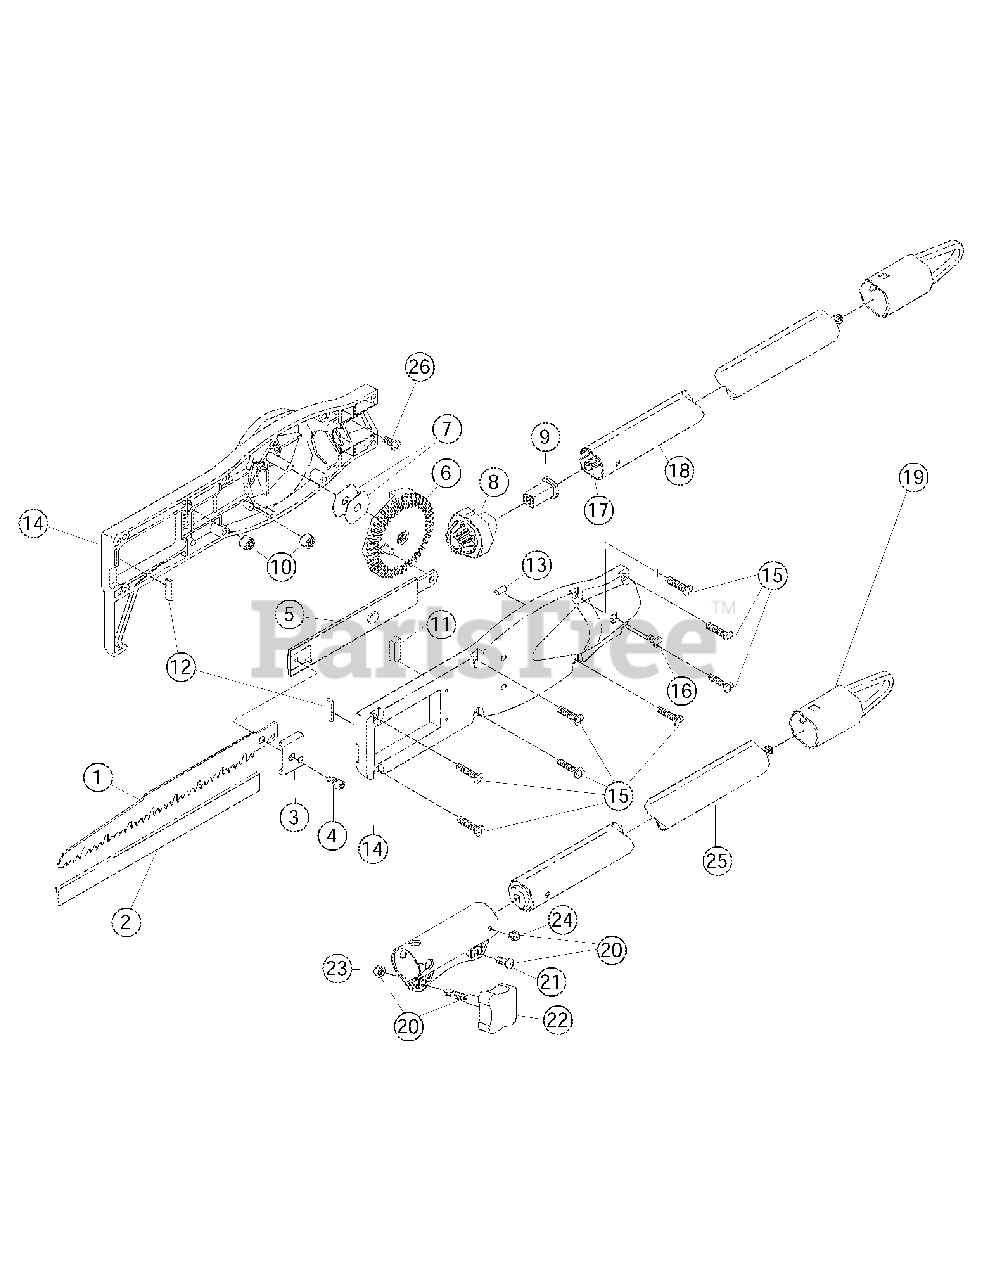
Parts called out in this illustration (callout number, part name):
1	Blade (2 pack)
2	Blade Cover
3	Blade Clamp
4	Blade Clamp Screw & Washer Assembly
5	Arbor Assembly
8	Pinion Bevel Gear
10	Slide Bushing
12	Slider (2-pack)
13	Rubber Plug
14	Housing set
15	Housing Screw (8 required)
16	Anti-Rotation Screw
17	Drive Shaft Assembly
18	Drive Shaft Housing Assembly
19	Hanger
20	Coupler (includes items 21-24)
22	Adjustment Knob
23	Knob Retaining Nut
25	Extension Boom & Flex Shaft Assembly
26	Anti-Rotation Screw
